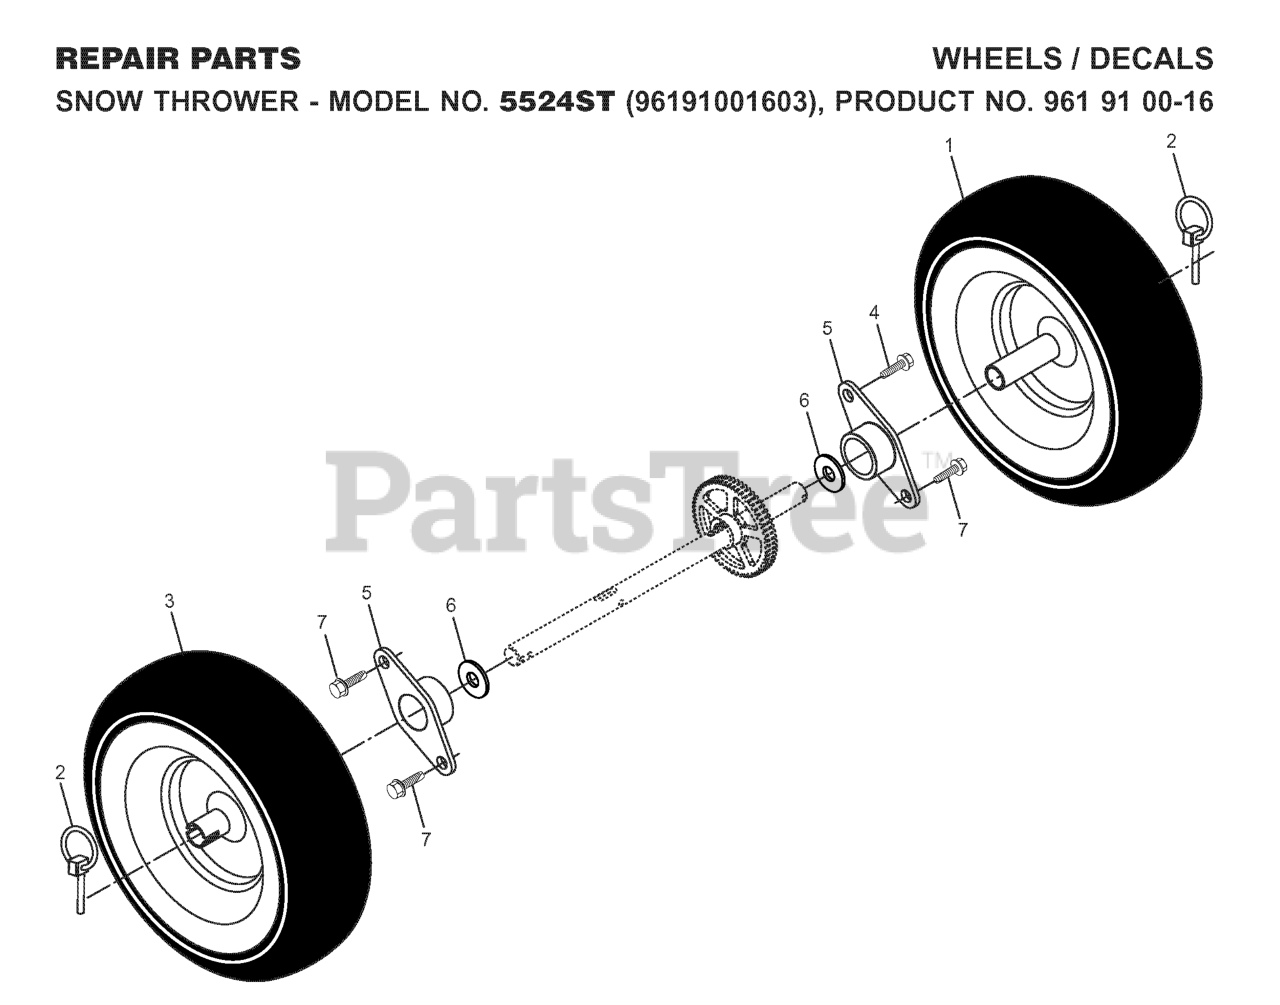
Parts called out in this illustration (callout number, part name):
1	WHEEL.ASM.LT.16"GRY.XTRAC
2	PIN KLIK, 1/4
3	WHEEL.ASM.RT.16".GRAY.XTRAC
5	BEARING, AXLE
6	WASHER TRUST 1"
7	Screw 5/16-18 x 1/2 Hex, Self Tapping 5/16-18 x 1/2
